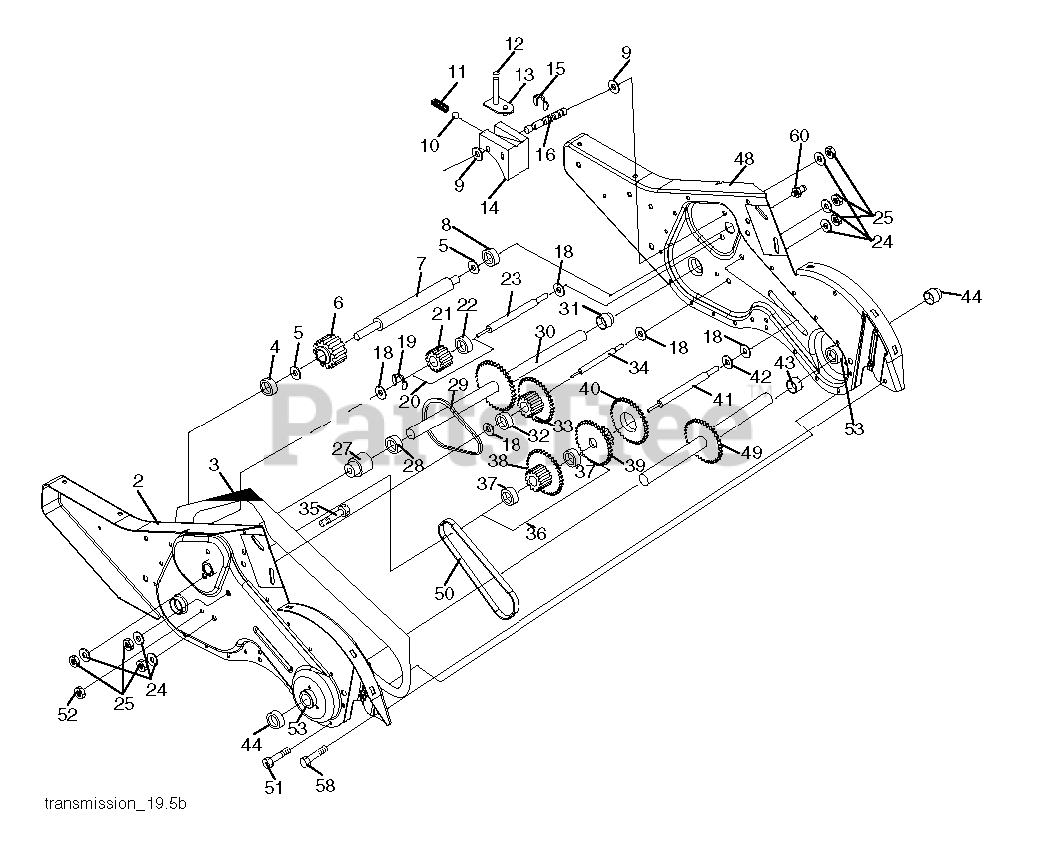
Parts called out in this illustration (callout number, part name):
1	TRANSMISSION ASM.
2	GEARCASE.ASM.CRT.LH.W/BEARING
3	GASKET
4	NEEDLE BRNG LT
5	THRUST WASHER
6	GEAR.PINION.INPUT
7	SHAFT.INPUT."D".TILLER
8	BEARING TI
9	WASHER, SEAL (2 2)
10	STEEL BALL KIT
11	SPRING-SHIFT CRT
13	BRACKET ASM.SHIFT.CRT
14	SHIFT FORK TI
16	SHAFT.SHIFTER.TILLER
20	GEAR ASSY CRT
21	GEAR-REV IDLR CRT
22	NEEDLE BEARING TI
24	LOCKWASHER
25	NUT.ASF.HEX.7/16
27	BEARING, SHAFT LH CRT
30	GROUND SHAFT ASS'Y
31	BEARING, SHAFT RH CRT
33	SPRCKT 8 GEAR CRT
34	SHAFT.SECONDARY.REDUCTION.CRT
35	SCRW WHIZ LOK CRT
36	SPROCKET.ASM.W/BEARING.TILLER
37	BEARING
38	SPROCKET, TINE
41	SHAFT.REDUCTION.TILLER
42	BRNG RACE T
44	SEAL ASM, OIL
48	GEARCASE.ASM.CRT.RH.W/BEARING
49	TINE SHAFT
50	CHAIN.TILLER
51	SCREW
53	KIT.BEARING.TILLER.
58	BOLT SHOULDER 1/4-20 UNC X.875
60	FITTING.GREASE.TAPERED
